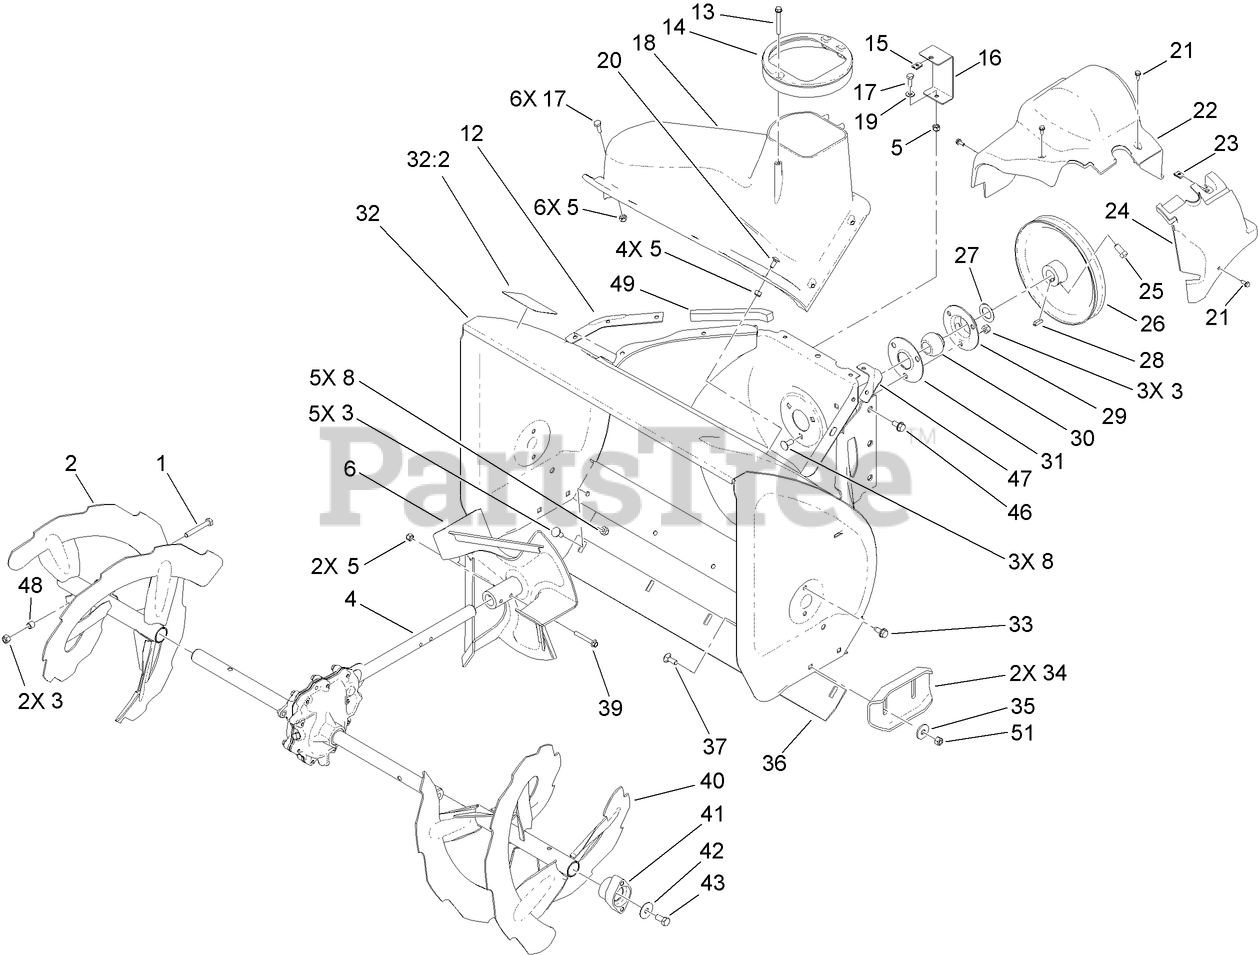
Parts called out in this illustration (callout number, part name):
1	SCREW-HH
2	RH AUGER ASM
3	NUT-LOCK, NI
5	NUT-LOCK, NI
6	IMPELLER ASM
8	SCREW-CARR
12	SEAL-FLANGE, COVER
13	SCREW-PLASTITE
14	GUIDE-CHUTE
15	NUT-SPEED
16	BRACKET-COVER, CLIP NUT
17	SCREW-HH
19	WASHER-FLAT
20	BOLT-CARR
21	SCREW-HWH
22	COVER-BELT
23	NUT-SPEED
24	COVER-EXTENSION, BELT
25	SCREW-SET, SQH
27	WASHER-THRUST
28	KEY-WOODRUFF
29	FLANGE-CUP, BEARING
30	BEARING-BALL
31	FLANGE-CUP, BEARING
32	HOUSING-AUGER, 26 INCH
32:2	DECAL-DANGER
33	SCREW-HWHTF
35	WASHER
36	SCRAPER-FIXED
37	SCREW-CARR
39	SCREW-HH
40	LH AUGER ASM
41	BEARING-AUGER
42	WASHER
43	SCREW-HH
46	SCREW-HWHTF
48	SPACER
49	SEAL-HOUSING
51	NUT-HF, NI
